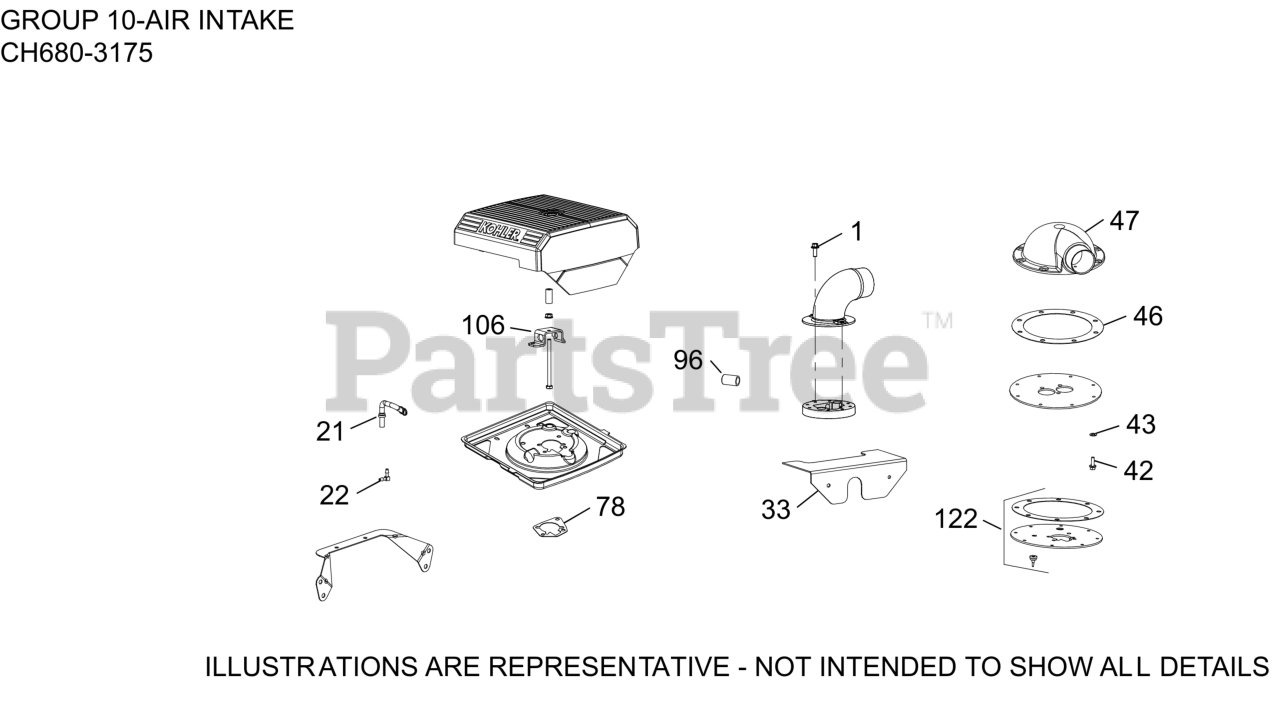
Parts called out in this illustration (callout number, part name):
1	SCREW, THREAD FORMING
1	SCREW, FLG M6X1.0X16
21	HOSE, EVAP
22	CONNECTOR, EVAPORATIVE HOSE
33	SHIELD, DEBRIS
42	SCREW, HVY FLG M5X.8X16
46	GASKET, AIR CLEANER ADAPTER
47	AIR INTAKE ADAPTER
78	GASKET, AIR CLEANER BASE
96	MASKING CAP
106	AIR CLEANER BRACKET
122	KIT, PLATE ADAPTER
NI	CONNECTOR, EVAPORATIVE
